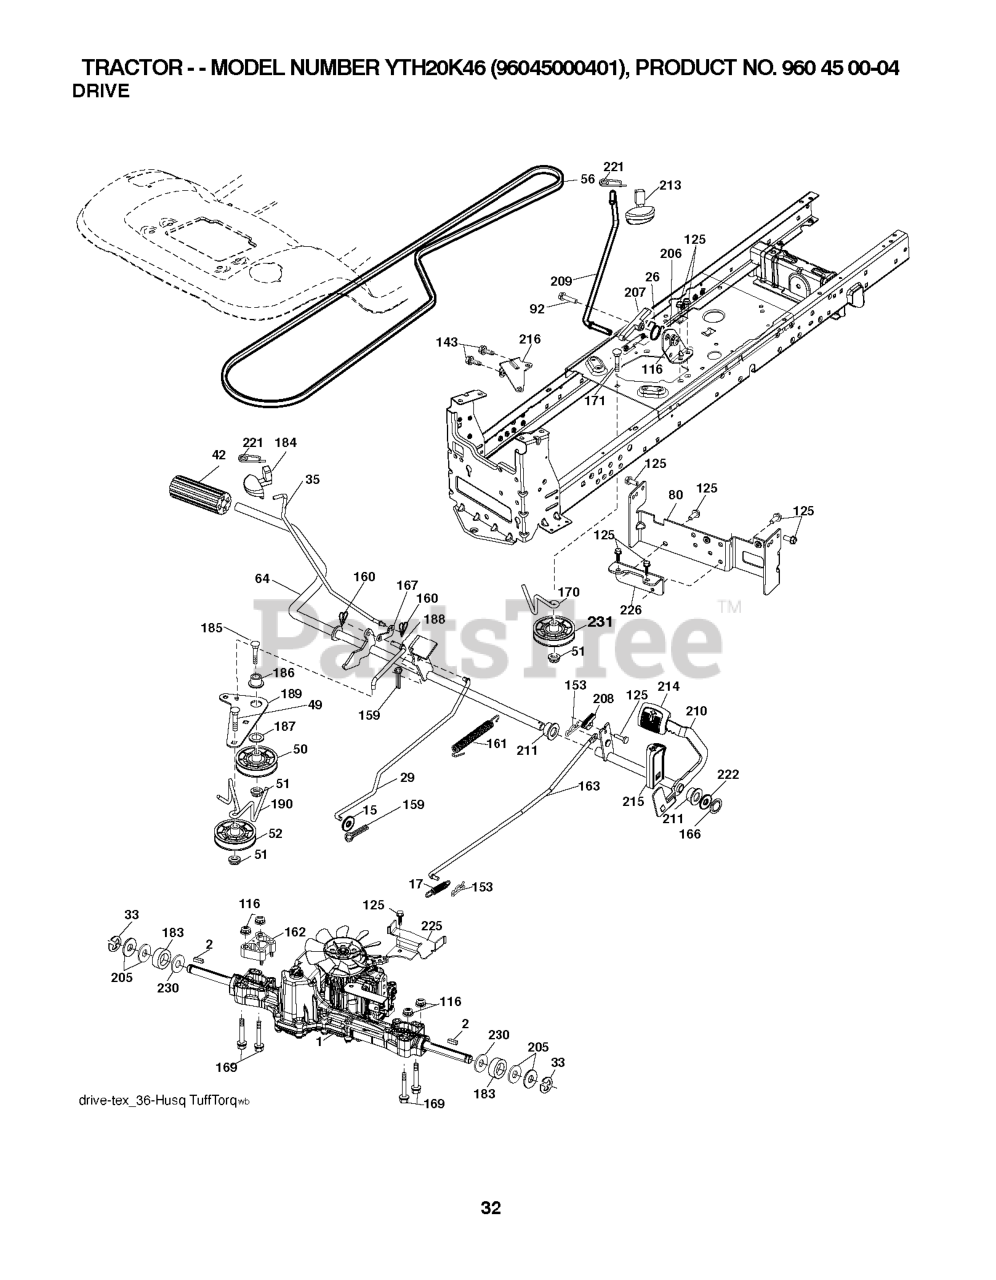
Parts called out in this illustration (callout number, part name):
1	TRANSAXLE, TUFFTORQ K46
2	SQUARE KEY
15	WASHER
17	SPRING.BRAKE.K46.GREEN
26	SPRING.RETURN.CRUISE
29	ROD.BRAKE.K46
35	ROD.BRAKE.PARKING.GT.H
42	PEDAL COVER T
50	IDLER.FLAT.910.OFFSET
51	NUT LOCK FLG 3/8-16 UNC
52	IDLER.V-GROOVE.910.OFFSET
56	V-BELT.MOWER.92.40.42/K46
64	SHAFT.ASM.PEDAL.BRK.CNTR
80	STRAP TORQUE
92	BOLT
116	NUT LOCK HEX FLANGE 5/16-18
125	SCREW
143	Screw 5/16-18 x 1/2 Hex, Self Tapping 5/16-18 x 1/2
153	RETAINER M
159	COTTER PIN
160	RETAINER CLIP
161	SPRING.RETURN.CLUTCH.2006
162	SPACER.TRANSAXLE.18&22
163	ROD.CONTROL.PEDAL.K46
166	NUT.PUSH.625.2006
167	LATCH.BRAKE.SPRING
169	BOLT.HEX.FLNG.5/16-18X3.75
170	KEEPER.V-IDLER.CENTER.
183	SPACER AXLE
184	HANDLE.PARKG.BRK.HUSQ X667
186	SPACER.RETAINER
187	WASHER 12/32X2X10GA
188	RP.LINK.CLUTCH.GROUND.DRIVE
189	BELLCRANK.GROUND.DRIVE.TEX.
190	KEEPER.BELLCRANK.DRIVE
206	BRKT.MOUNT.LATCH.CRUIS
207	LATCH.CONTROL.CRUISE
208	GEAR.SECTOR.CONTROL.CR
209	ROD.CONTROL.CRUISE.GT.
210	ROCKER.ASM.PEDAL.CONTR
211	BEARING.NYLON
213	KNOB.CONTROL.CRUSIE.HU
214	PEDAL.FORWARD.TEX.GT.4
215	PEDAL.REVERSE.TEX.GT.4
216	BRACKET.PULLEY.IDLER.W/TEX
221	RETAINER.SPRING.CLIP.H
222	WASHER 21/32 X 1-1/4 X 10 GA.
225	KEEPER.BELT.TRANSAXLE.K46
226	BRACKET.MOUNT.TORQUE.K46.TLT
230	WASHER.HARDENED
231	IDLER.V-GROOVE.1.688.OFFSET
